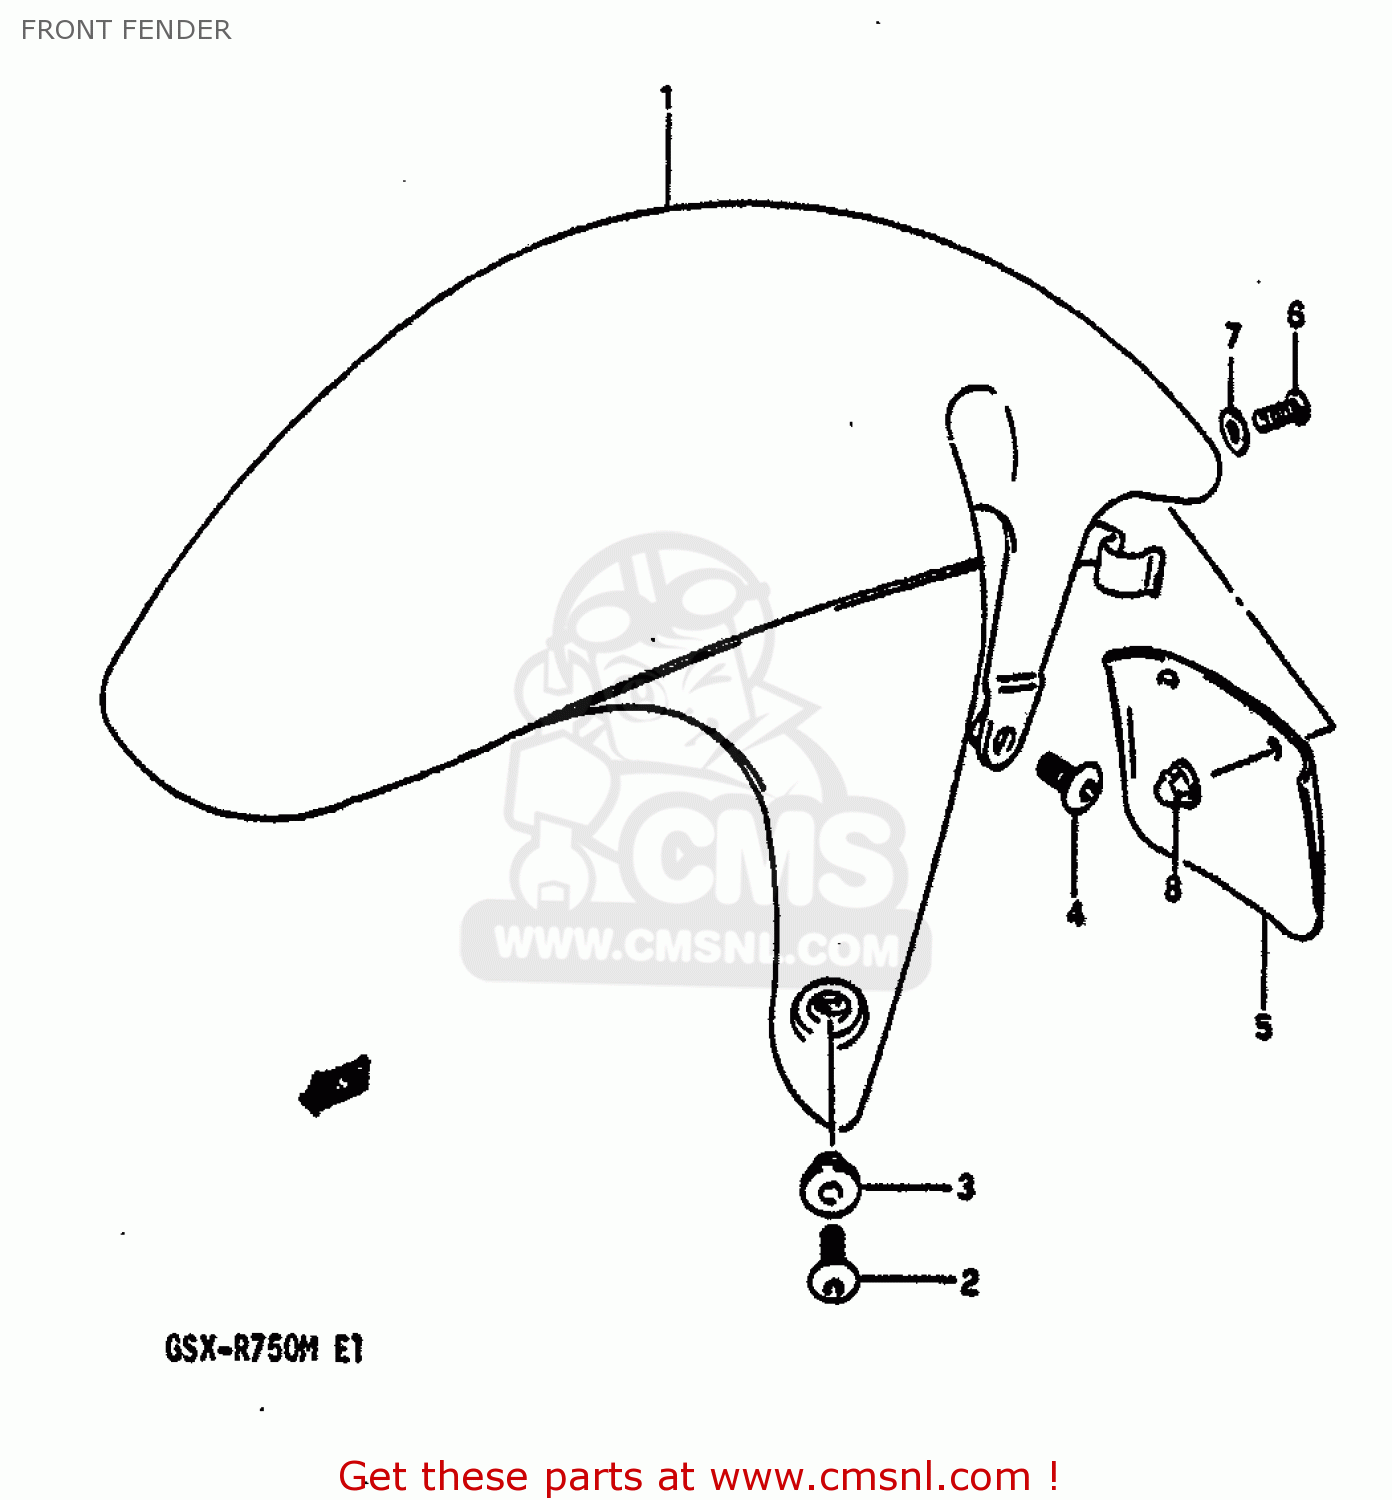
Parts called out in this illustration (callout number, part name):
1	FENDER,FRONT
2	SCREW(6X16)
3	WASHER(6.3X16X1.5)
4	SCREW(8X16)
5	MUD GUARD,FR.F
6	SCREW M5X12 DIN 7985/N
7	WASHER
8	NUT 5MM
